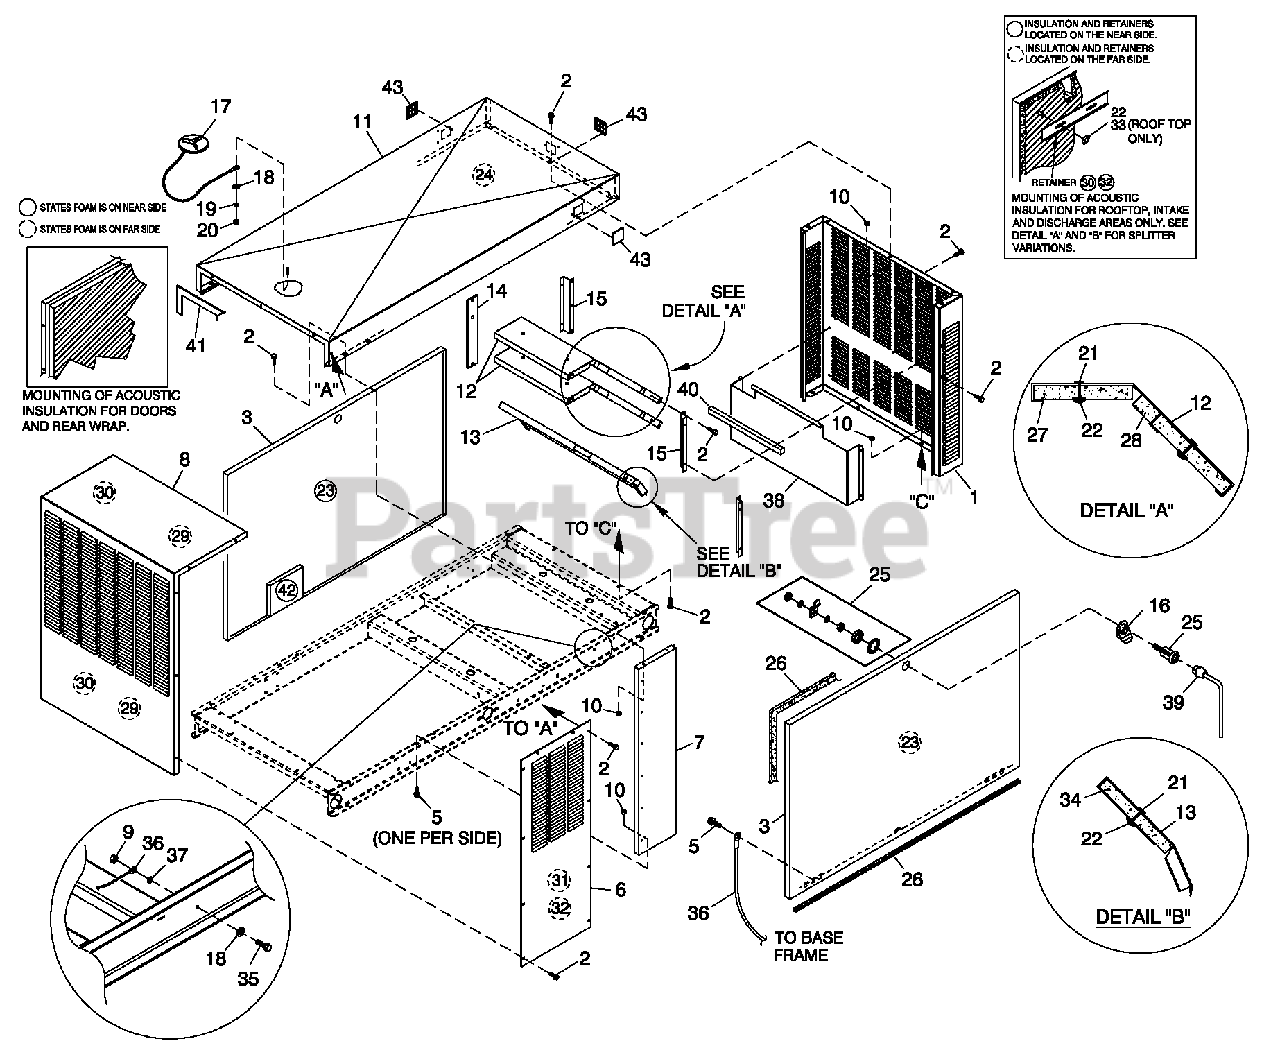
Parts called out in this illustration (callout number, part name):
1	REAR WRAP C2G2 60KW
2	SCREW THF M6-1 X 16 N WA Z/JS
3	DOOR C2
4	RIVET POP.1875 X .450 SS
5	SCREW TH-FRM M6 W/CAP SHKPRF W
6	DUCT DSCHRG LH&RH
7	FRONT CORNERS C2
8	DUCT DISCHARGE C2
9	NUT HEX M6X 1.0 G8YEL CHR
10	NUT HEX LOCK M6-1.0 SS NY INS
11	ROOF C2
12	SLITTER C4
13	SPLITTER LOWER C4
14	SPLITTER STINGER C2
15	SUPPORT SPLITTER LH C2
16	TAB PULL
17	ASSEMBLY COVER ACCESS
18	WASHER FLAT 1/4-M6 ZINC
19	WASHER LOCK M6-1/4
20	NUT HEX 1/4-20 STEEL
21	INSULATION RETAINMENT HANGER
22	WASHER SELF LOCKING DOME #4-40
23	INSULATION DOOR C2
24	INSULATION ROOF TOP
25	VISE-ACTION LATCH SLOTTE D CIR
26	GASKET EXTRUDE D TRIM (328" LG)
27	INSULATION SPLITTER
28	INSULATION SPLITTER
29	INSULATION DUCT
30	RETAINER INSULATION (820)
31	INSULATION DUCT SI DES
32	RETAINER INSULATION (450)
33	WASHER SELF LOCKING DOME #8-32
34	INSULATION LOWER SPLITTER
35	SCREW HHC M6-1.0X 20 G8.8
36	ASSY WIRE 14 AWG 34.8" GRN/YEL
37	WASHER SHAKEPROOFINT 1/4
38	DEFLECTOR INTAKE 2.4L G2 TURBO
39	KEY VISE-ACTION LATCH SLOT CIR
40	TAPE FOAM 1X1 (17.25" LG)
41	STRIP SEALANT 1/8 X 1 (44.52" LG)
42	FOAM 300 X 300 THERMAL ACO
43	RF COVER PLATE-PLASTIC-BISQUE
